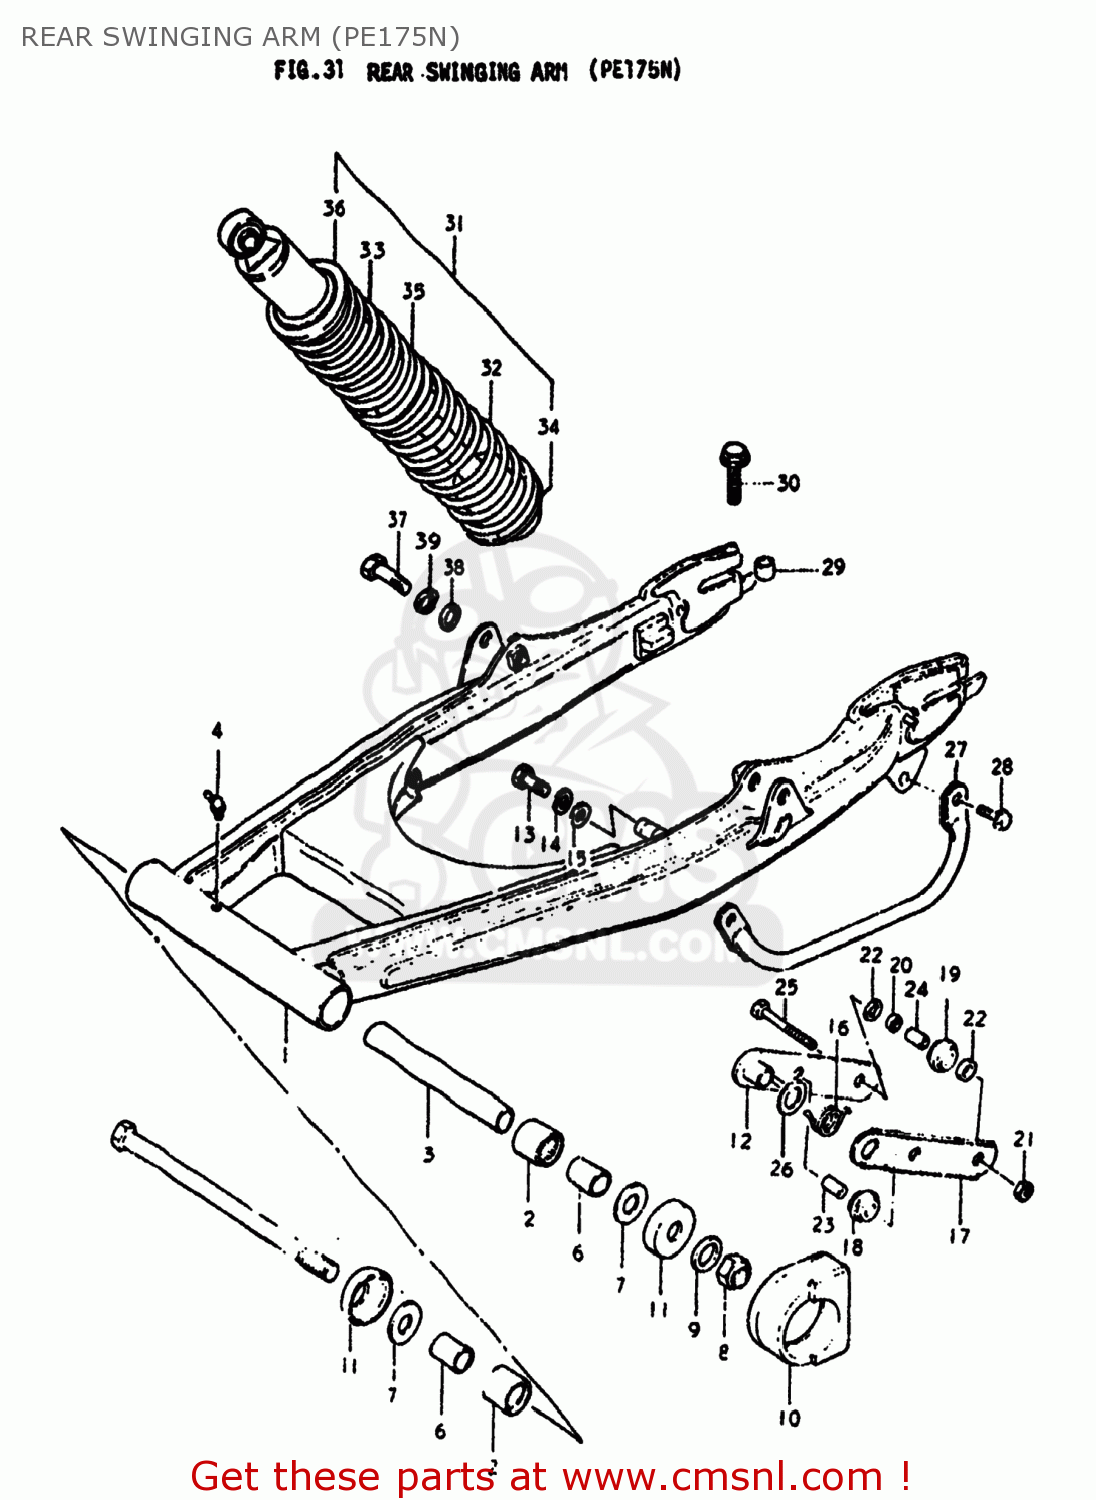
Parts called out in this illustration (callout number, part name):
1	SWING ARM ASSEMBLY,REAR
2	ROLLER BEARING (17X24X2
3	SPACER,REAR SWING ARM PIVOT
4	NIPPLE,GREASE
5	SHAFT,REAR SWING ARM
6	SPACER,RR SWGARM PIVOT
7	WASHER
8	NUT 12MM
9	WASHER
10	BUFFER,CHAIN TOUCH DEFENSE
11	COVER,RR SWGARM DUST SEAL
12	TENSIONER,CHAIN
13	BOLT
14	LOCK WASHER
15	WASHER
16	SPRING
17	PLATE,CHAIN TENSIONER OUTER
18	RUBBER,CHAIN GUARD
19	ROLLER,CHAIN TENSIONER LWR
20	BEARING(10X14X15)
21	NUT 6MM
22	SEAL,OIL(10X14.4X3.5)
23	SPACER(6.5X10.5X22.5)
24	SPACER(6.2X10X22.5)
25	BOLT
26	WASHER
27	GUARD
28	BOLT
29	SPACER (8.2X14X16.5)
30	BOLT
31	ABSORBER ASSEMBLY,REAR SHOCK
32	SPRING
33	SPRING
35	SPRING
36	GUIDE,SPRING
37	BOLT 10X40
38	WASHER
39	LOCK WASHER
